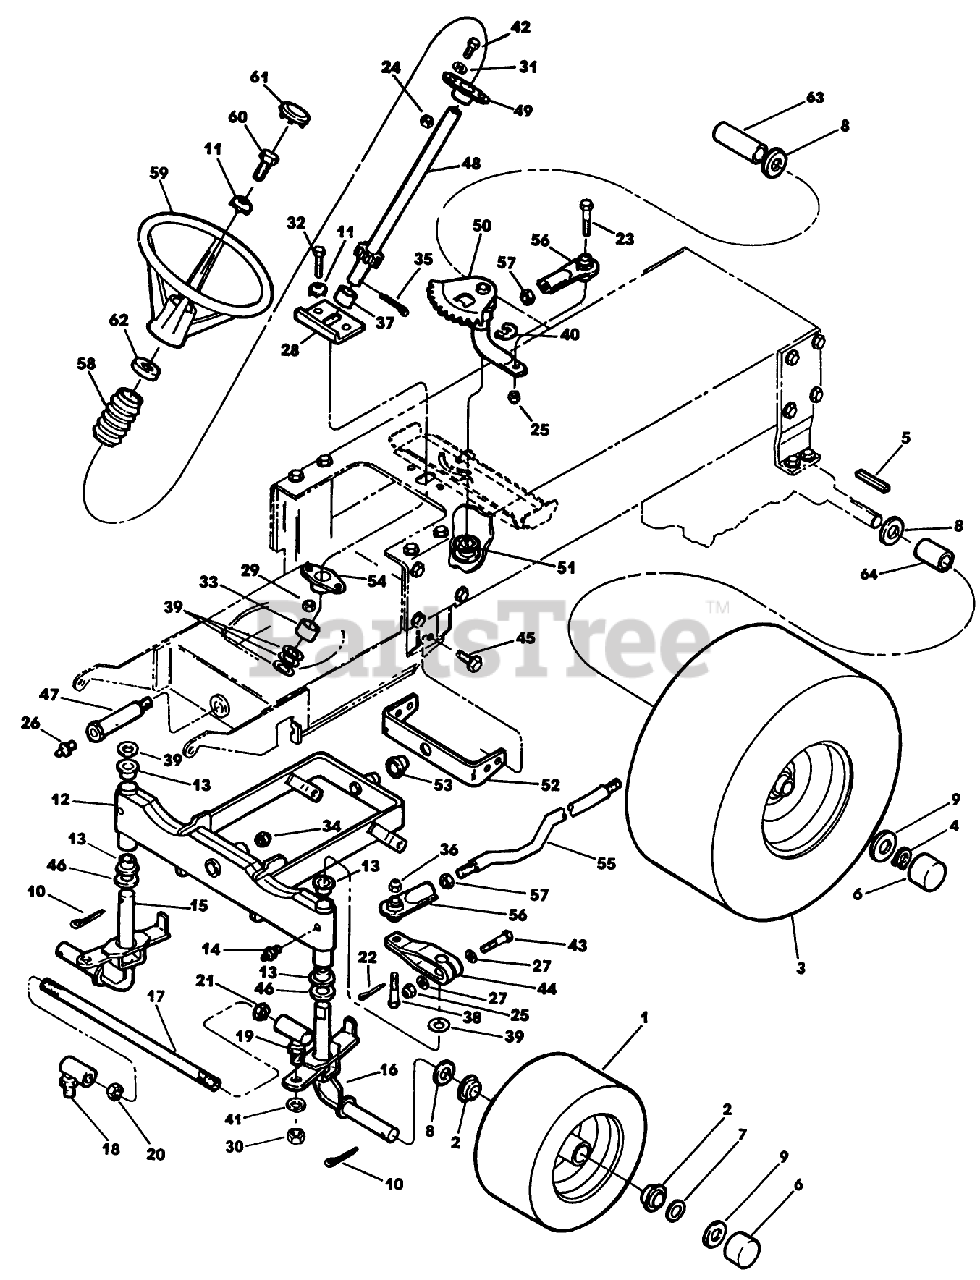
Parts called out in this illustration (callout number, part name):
9	WASHER
13	BEARING - BRONZE
17	ROD, STEER 1/2
18	BALL JOINT R.H.
19	BALL JOINT L.H.
24	NUT-LOCK, CONE
25	NUT-LOCKING
27	WASHER
29	NUT
32	SCREW
34	NUT-HEX
37	SPACER
39	SPACER
42	SCREW-HH
46	WASHER - THRUST
49	BEARING AY.
56	BALL JOINT
57	NUT-HEX
60	SCREW - HEX
61	CAP
